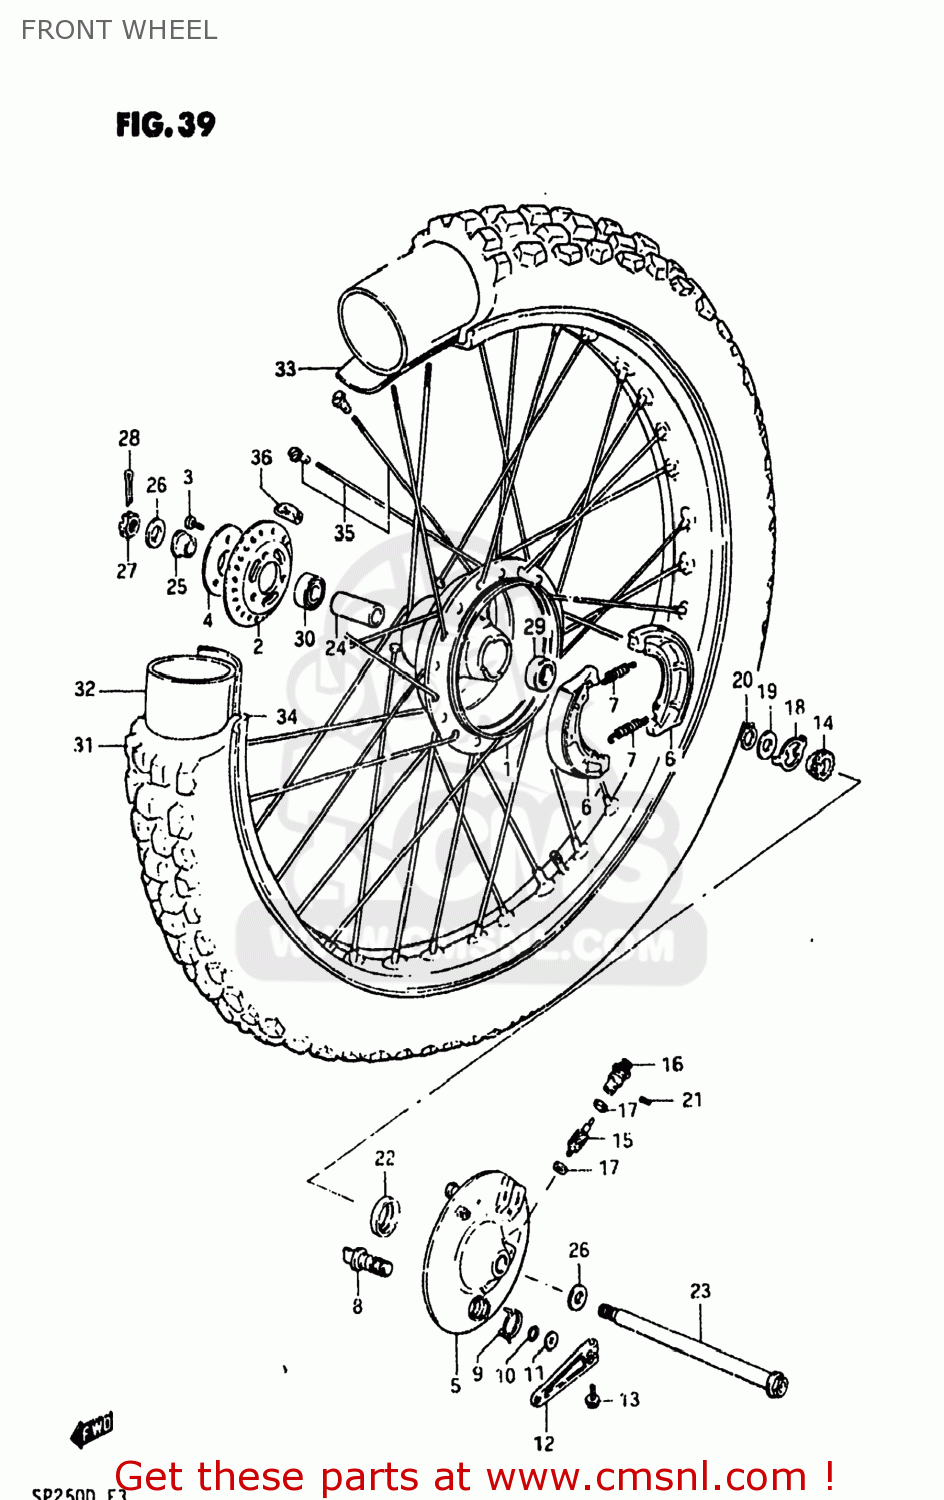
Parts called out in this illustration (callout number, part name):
23	AXLE,REAR
24	SPACER (12.6X19X52)
25	SPACER,FR AXLE,R
26	WASHER
27	NUT, REAR AXLE
28	COTTER PIN
29	BEARING
30	BEARING, RH
31	TIRE,FRONT
32	TUBE
33	PROTECTOR,WHEEL,INNER
34	RIM,FRONT WHEEL
35	SPOKE SET,FRONT
36	BALANCER,WHEEL (50G)
